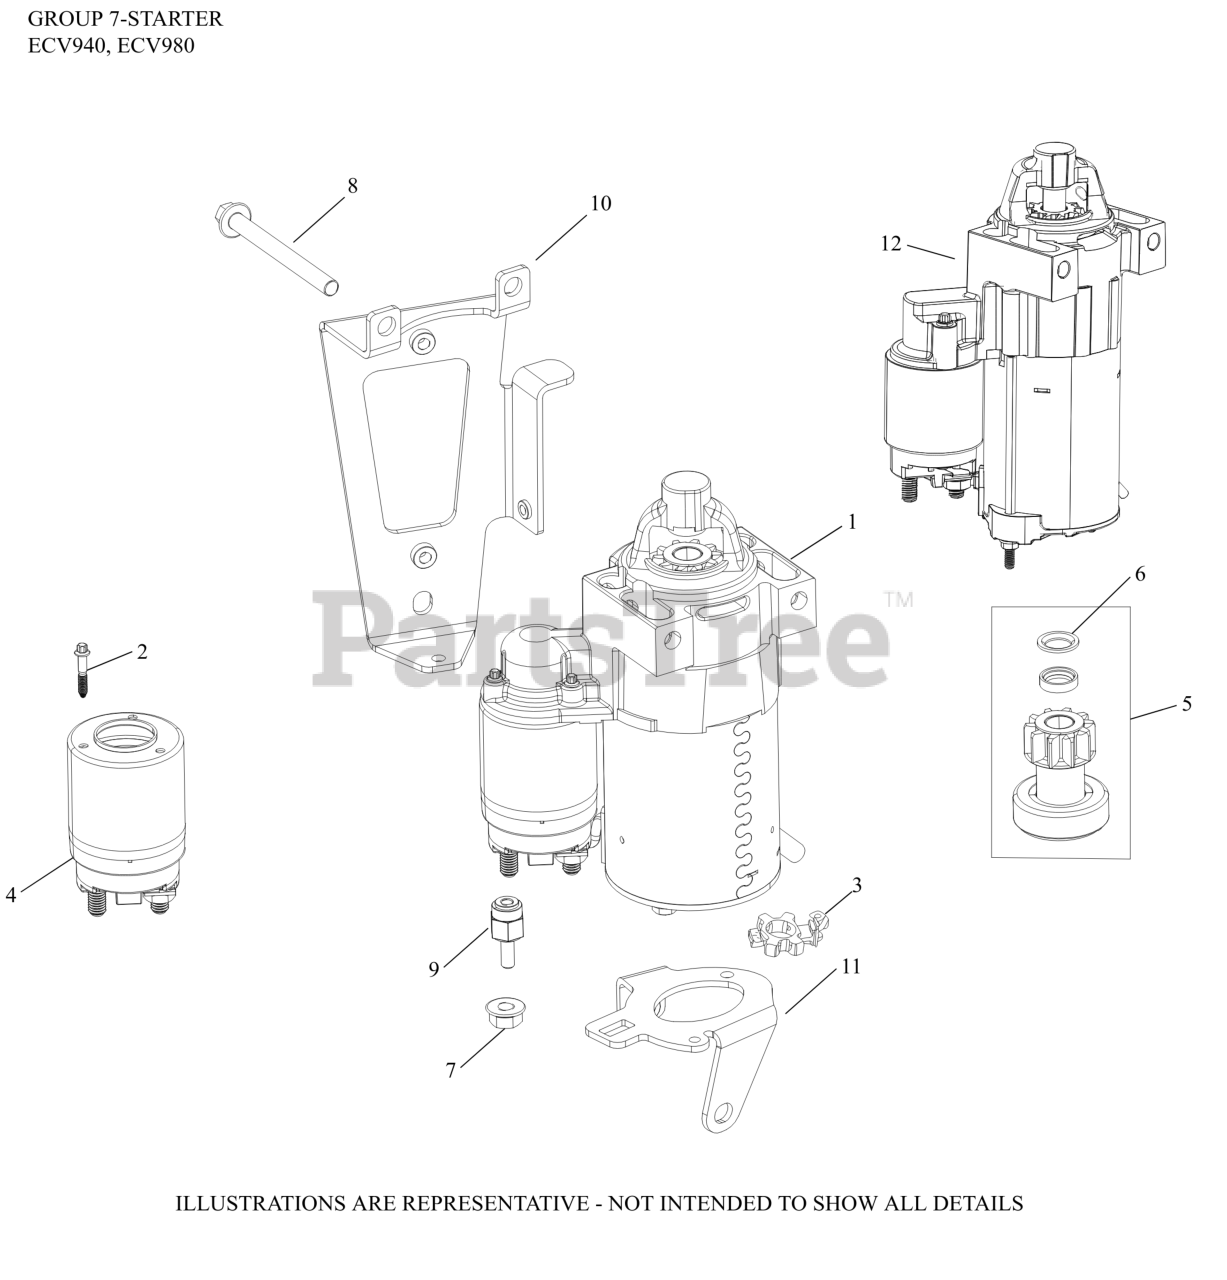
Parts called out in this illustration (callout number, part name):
1	STARTER, SOLENOID SHIFT-(#2509824S)
7	NUT, FLG M8X1.25
8	SCREW, FLG M8X1.25X80
